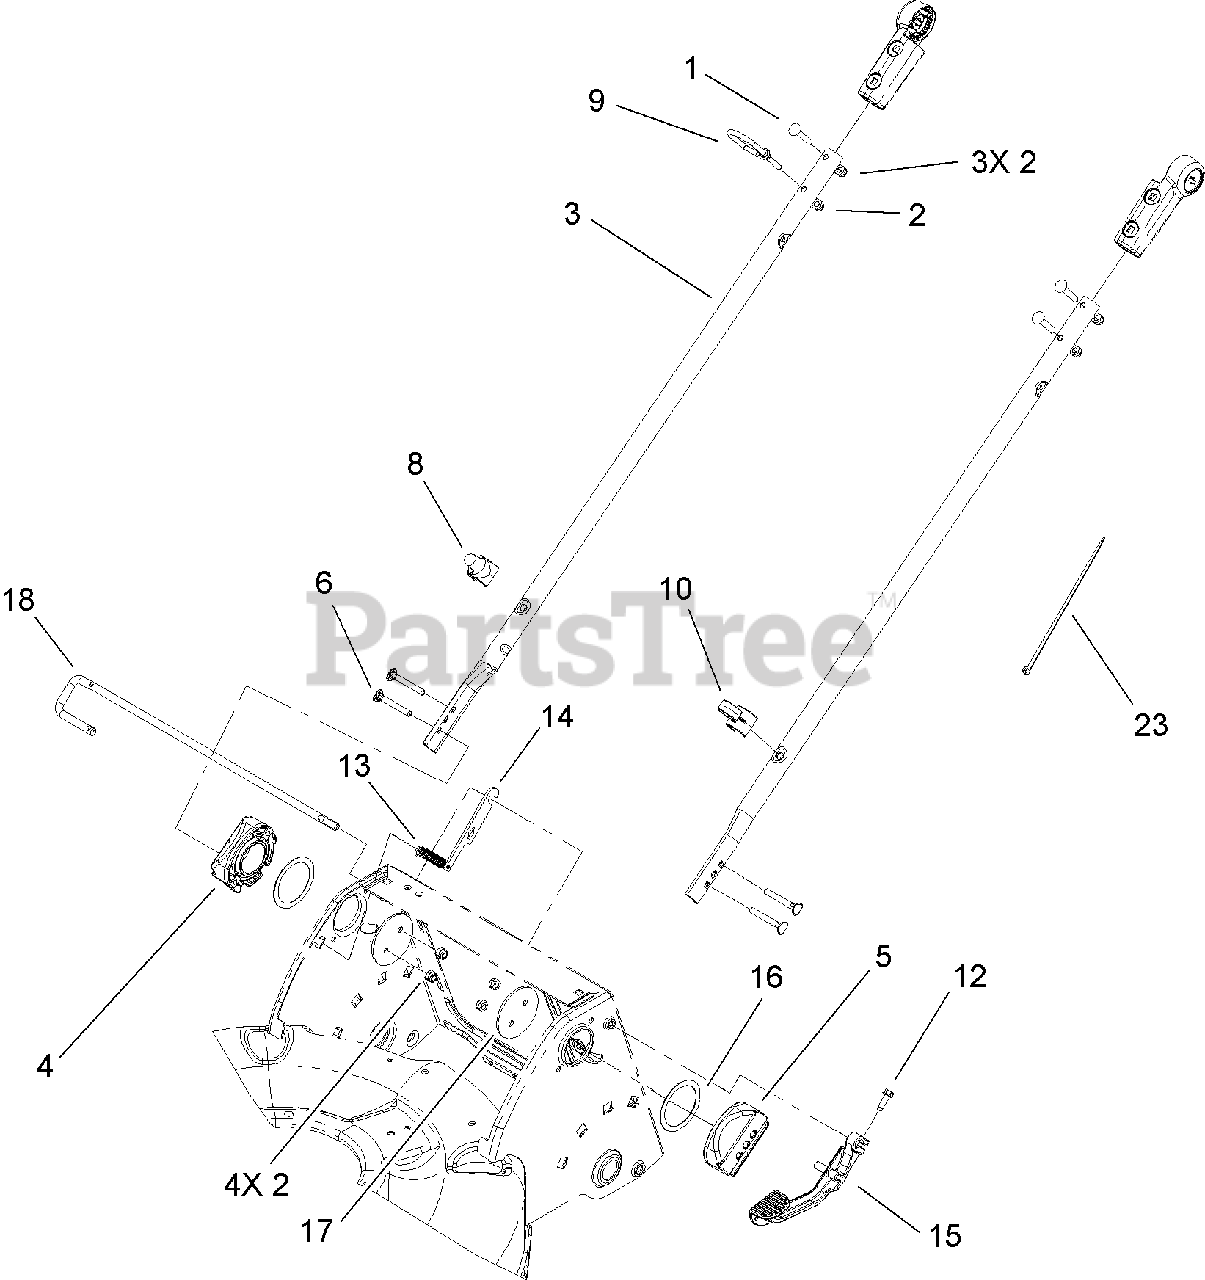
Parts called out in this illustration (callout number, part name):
1	SCREW-CARR
2	NUT-LOCK, NI
4	MOUNT-HANDLE, RH
5	MOUNT-HANDLE, LH
8	GUIDE-ROPE, LOWER
9	GUIDE-ROPE, UPPER
10	Guide-Cable
12	SCREW-HWHTF
13	SPRING-EXTENSION
14	PLATE-RELEASE ROD
15	LEVER-RELEASE
16	WASHER-NYLON
18	HANDLE-ROD, RELEASE
23	STRAP-TIE
